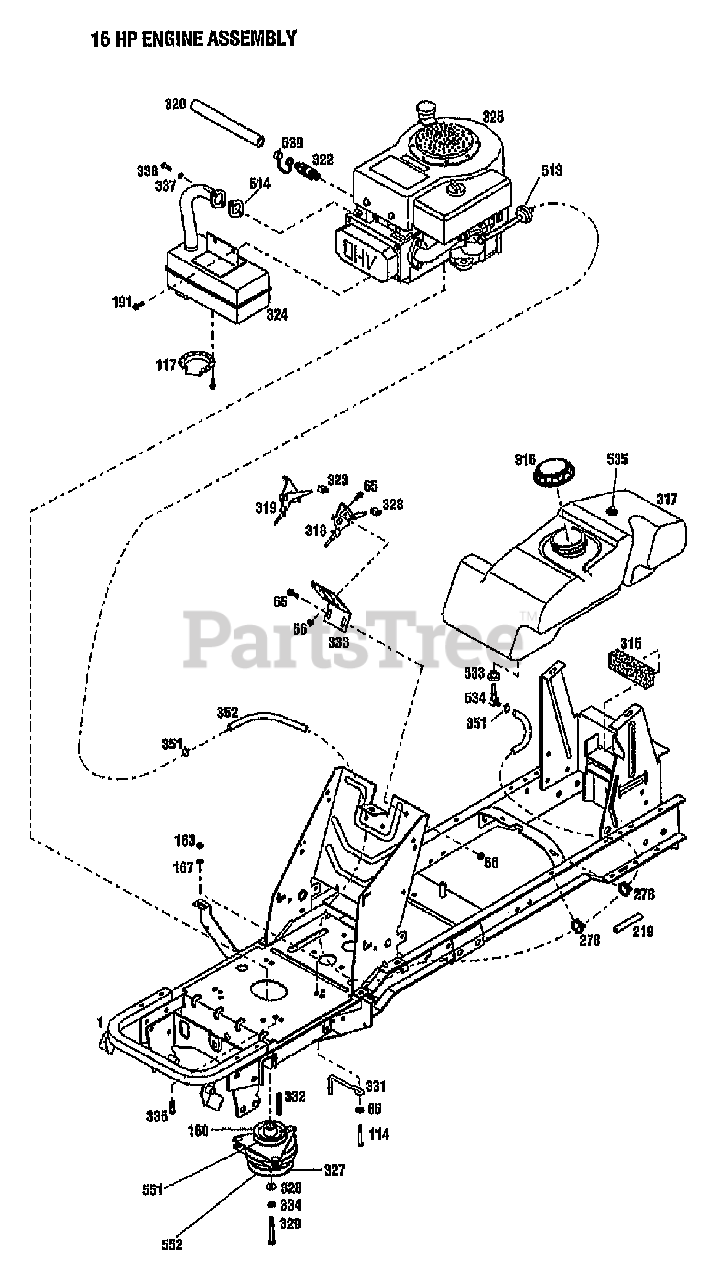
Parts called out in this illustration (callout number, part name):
1	ASSM-FRAME LTX
56	NUT-HF/LK 1/4-20 ZP
65	SCR-HH 1/4-20X.625
114	SCR-THRD FRM 3/8-16X1.50
117	DEFLECTOR-MUFFLER
160	PULLEY-ENGINE
163	NUT-HEX 3/8-16 ZP
167	WASHER-LK .375 @ DEPL
191	SCR-FLANGE 1/4-20X3/4 GR5
278	TIE-CABLE NYLON BLACK
315	PAD-FUEL TANK
316	CAP-FUEL
317	TANK-FUEL
318	CONTROL-THROTTLE
319	CONTROL-CHOKE
320	HOSE
322	ASSM-OIL VALVE
324	MUFFLER
325	ENGINE, B&S 15HP MODEL 28N707
327	CLUTCH-ELECTRIC
328	WASHER-SPEC 1.42X.468X.25 ZP
329	SCR-HH 7/16-20X3.00
331	CLUTCH-RETAINER
332	KEY-.25 SQ X 2.5
333	BRKT-MOUNTING CONTROL
334	WASHER-LK .438 ZP
335	SCR-HH 3/8-16X1.0 THDFM
337	WASHER-LOCK
338	SCR-HXSKT 5/16-18X.75 BO
351	CLAMP-HOSE
352	LINE-FUEL
513	FILTER-FUEL
514	MUFFLER GASKET
533	BUSHING-RUBBER
534	ELBOW-90 DEG (FUEL LINE)
535	VENT-FUEL TANK
539	CAP-OIL DRAIN
551	BEARING-UPPER CLUTCH
552	BEARING-CLUTCH LOWER
